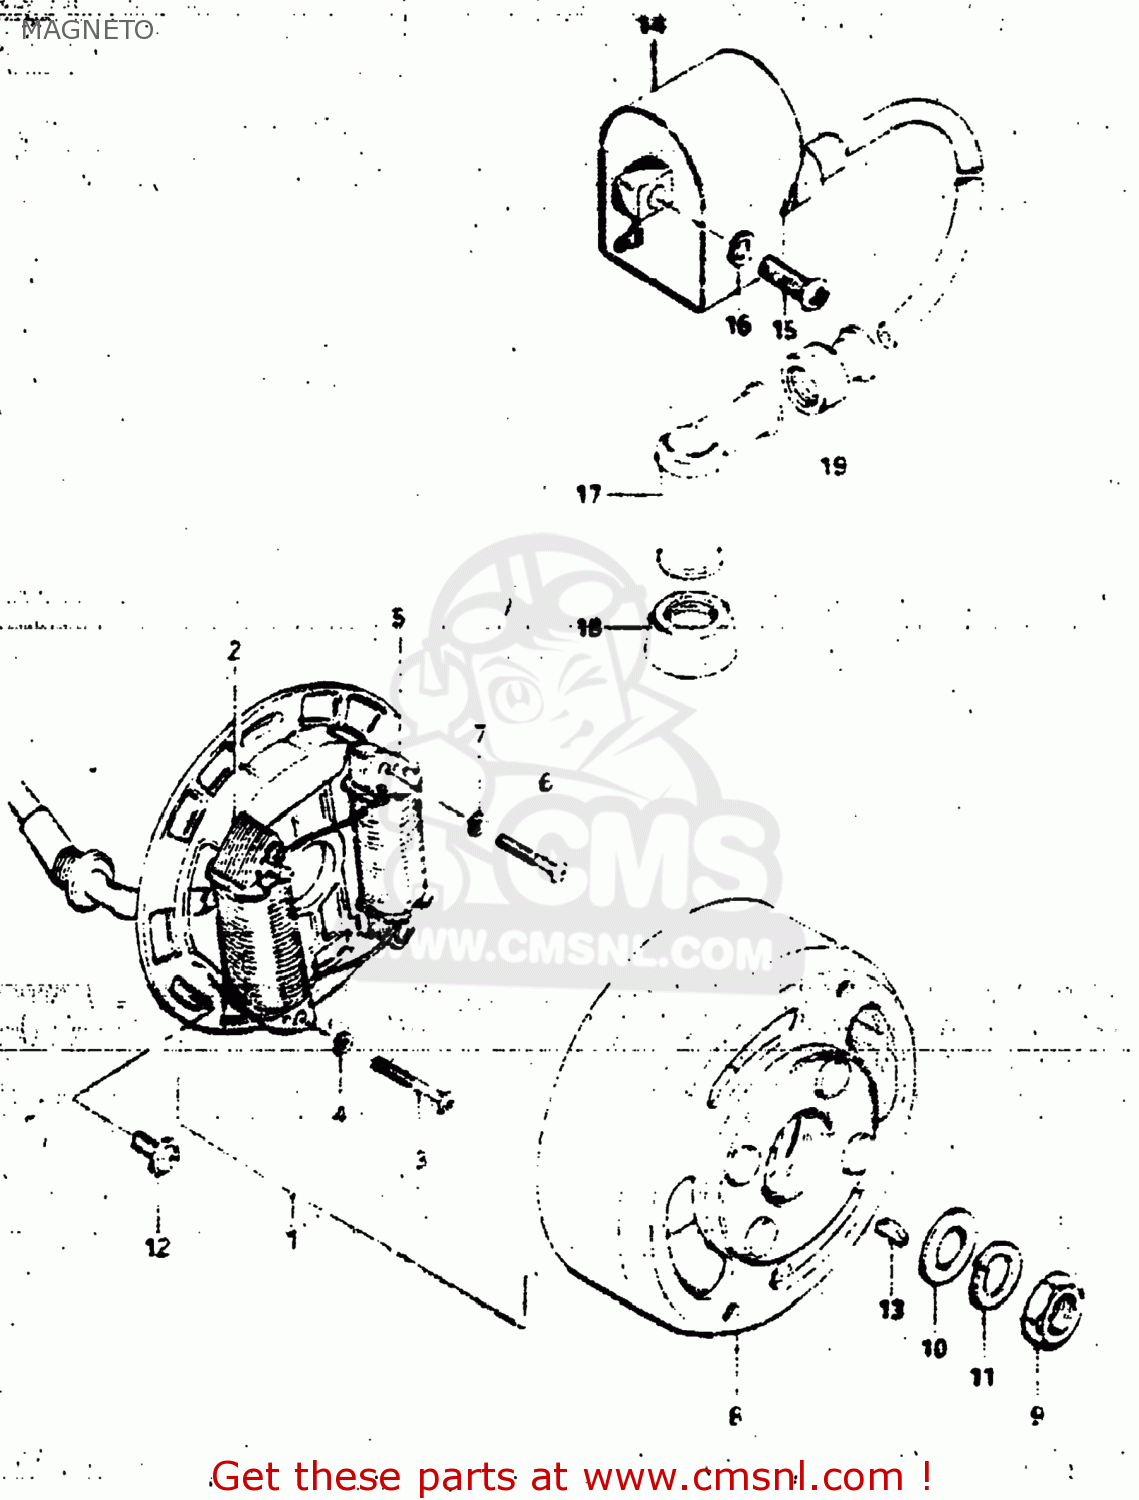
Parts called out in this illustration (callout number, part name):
1	STATOR ASSEMBLY
2	COIL,LIGHTING
3	SCREW (4X30)
4	LOCK WASHER
5	COIL
6	SCREW
7	LOCK WASHER
8	ROTOR,FLYWHEEL
9	NUT
10	WASHER
11	LOCK WASHER
12	SCREW(5X14)
13	KEY
14	UNIT & COIL ASSY,IGNITION
15	SCREW
16	LOCK WASHER
17	CAP ASSY,SPARK PLUG
18	SEAL,SPARK PLUG
19	SEAL,SPARK PLU
